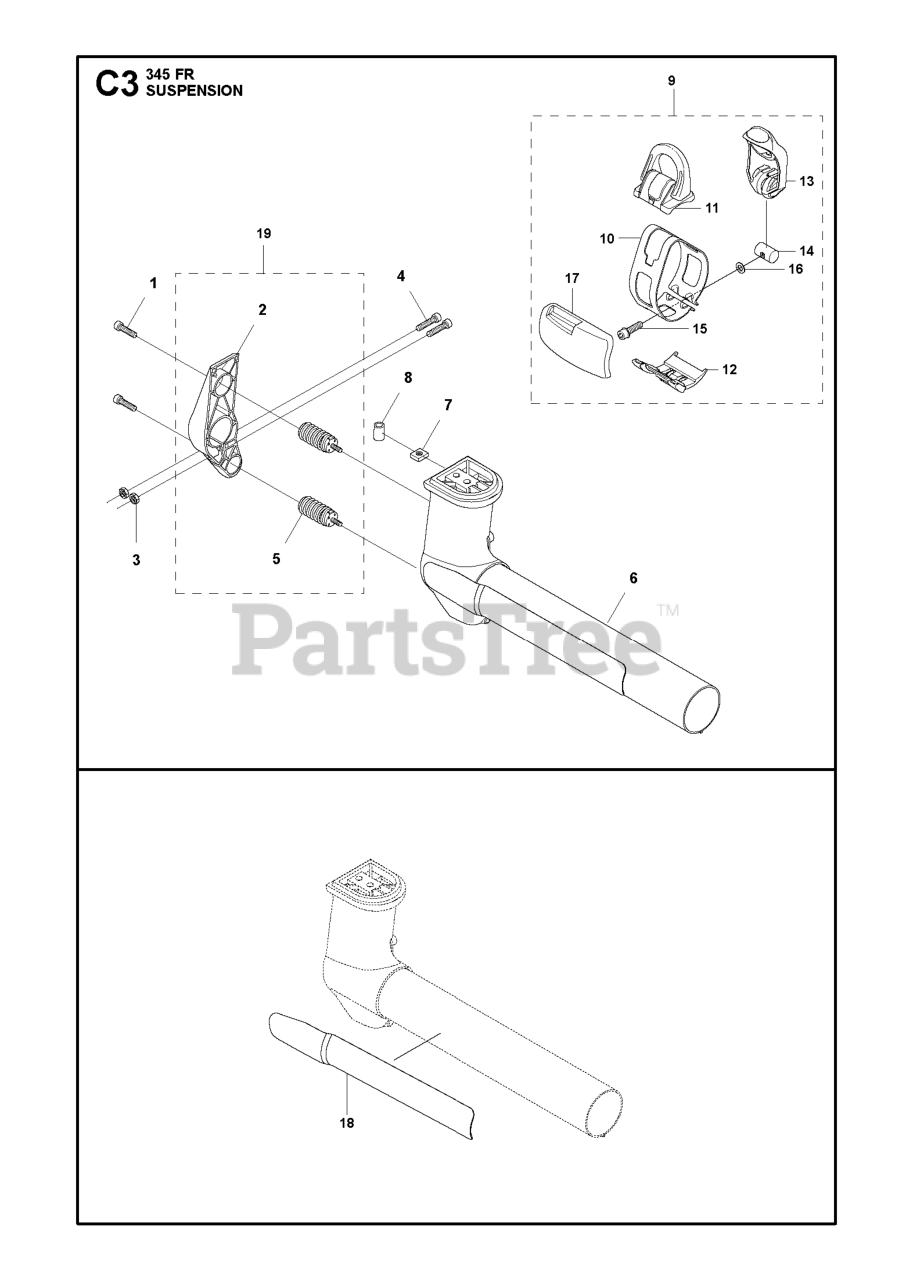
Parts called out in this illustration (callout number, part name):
2	HOLDER ANTIVIBRATION
5	ANTIVIBRATION ELEMENT ASSY
5	AV MOUNT
6	SUSPENSION HUSQVARNA
11	LOOP
12	GUIDE RAIL
16	WASHER 5.3X12
17	WEAR PROTECTION
18	WEAR PLATE ASSY
